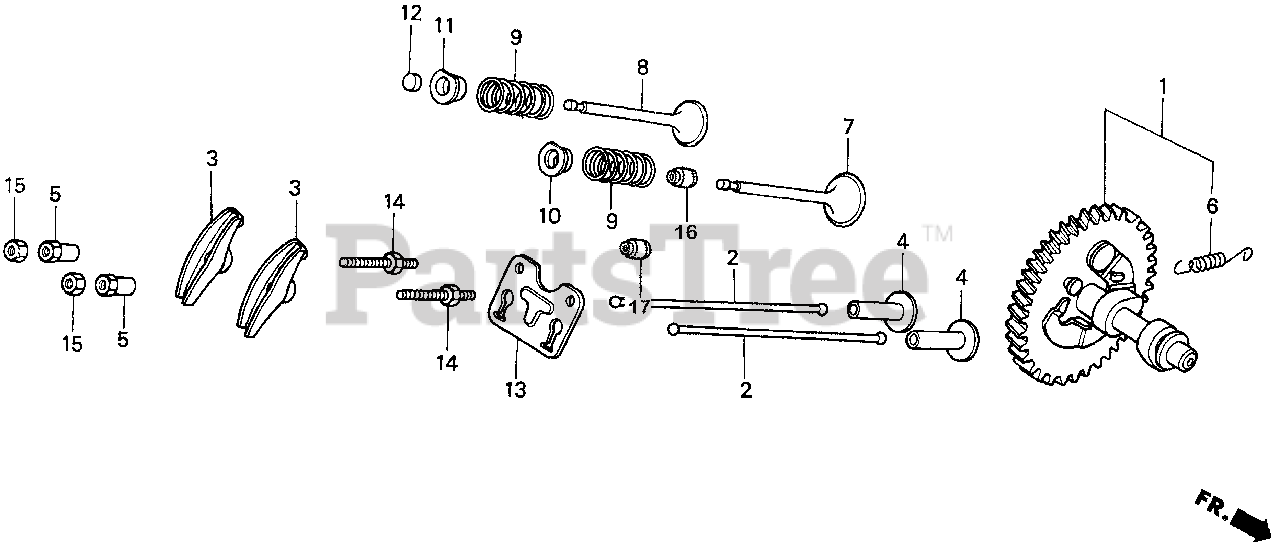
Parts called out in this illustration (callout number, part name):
1	CAMSHAFT ASSY.
2	ROD, PUSH
3	ARM, VALVE ROCKER
4	LIFTER, VALVE
5	PIVOT, ROCKER ARM
6	SPRING, WEIGHT RETURN
7	VALVE, IN.
8	VALVE, EX.
9	SPRING, VALVE
10	RETAINER, IN. VALVE SPRING
11	RETAINER, EX. VALVE SPRING
12	ROTATOR, VALVE
13	PLATE, PUSH ROD GUIDE
14	BOLT, PIVOT (8MM)
15	NUT, PIVOT ADJ.
16	SEAL, VALVE STEM
